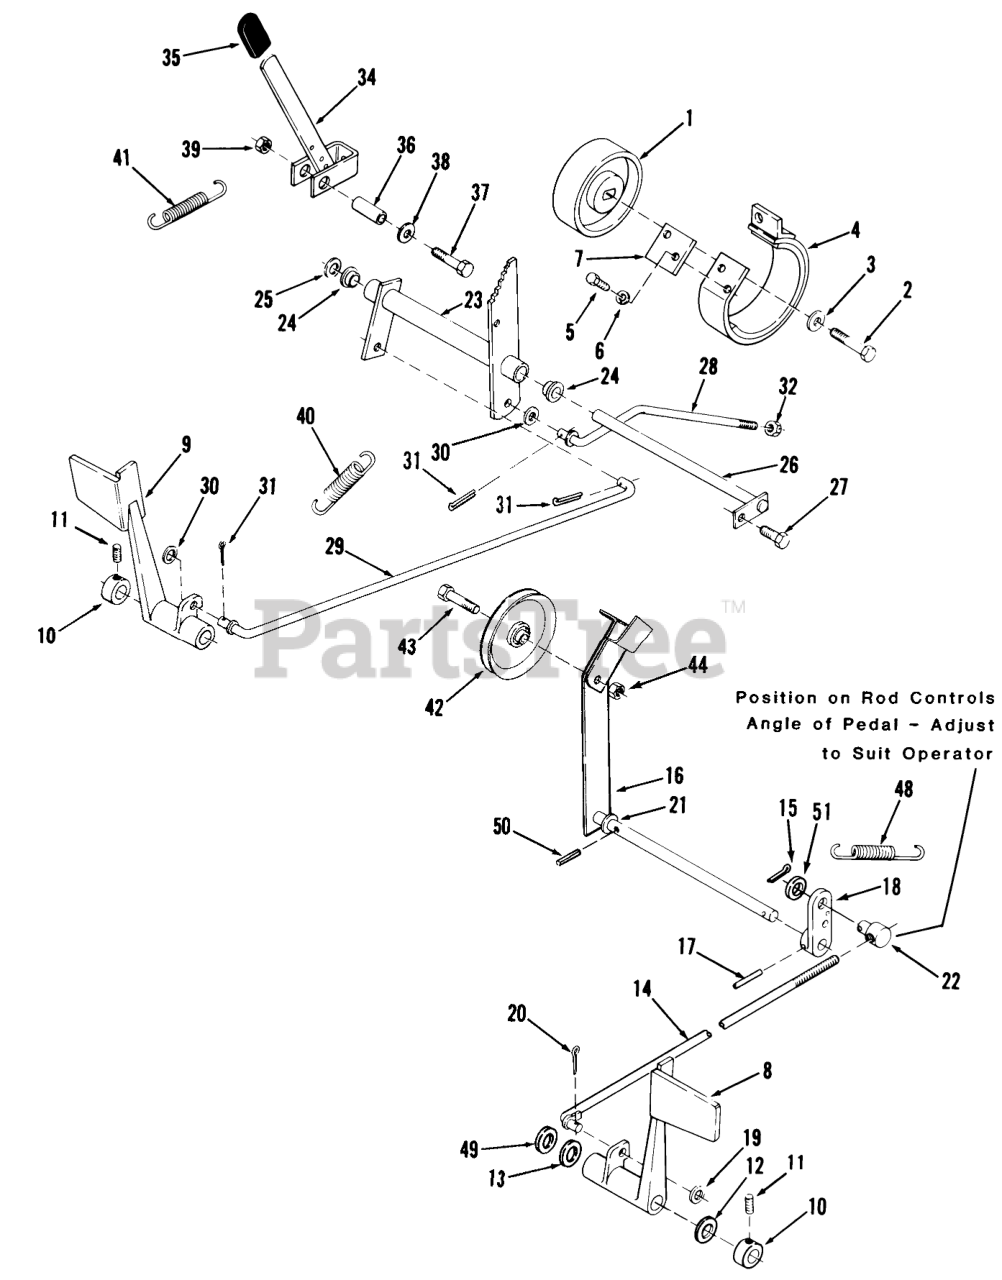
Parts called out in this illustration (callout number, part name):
1	DRUM-BRAKE
2	SCREW-HEX HD CAP
3	WASHER
4	BRAKE BAND ASM
5	H H C S
6	Washer
7	Plate-Stop
8	Pedal-Clutch
9	Pedal Brake
10	Collar
11	SCREW-SET
12	WASHER-BOWED
13	WASHER
14	ROD AND GUIDE ASM
14	ROD CLUTCH R
15	Cotter Pin
16	ASSY-IDLER ARM R
17	PIN-SPIROL
18	Arm-Clutch Rod
19	WASHER-NYLON
20	Pop Rivet
21	SHIM-WASHER
22	TRUNNION
23	Bellcrank Assy
24	BUSHING-FLANGED
25	Washer
26	ROD ASM
27	SCREW
28	ROD-REAR BRAKE
30	WASHER-NYLON
31	Pop Rivet
32	NUT
34	ASSY-BRAKE LEVER WAB
35	GRIP
36	SPACER
37	Bolt
38	Washer
39	LOCKNUT-FLANGE
40	SPRING-BRAKE
41	SPRING-EXTENSION
42	PULLEY-IDLER
43	BOLT-SPECIAL HEX
44	Nut
48	SPRING-CLUTCH
49	Washer
50	PIN-SPIROL
51	Washer
